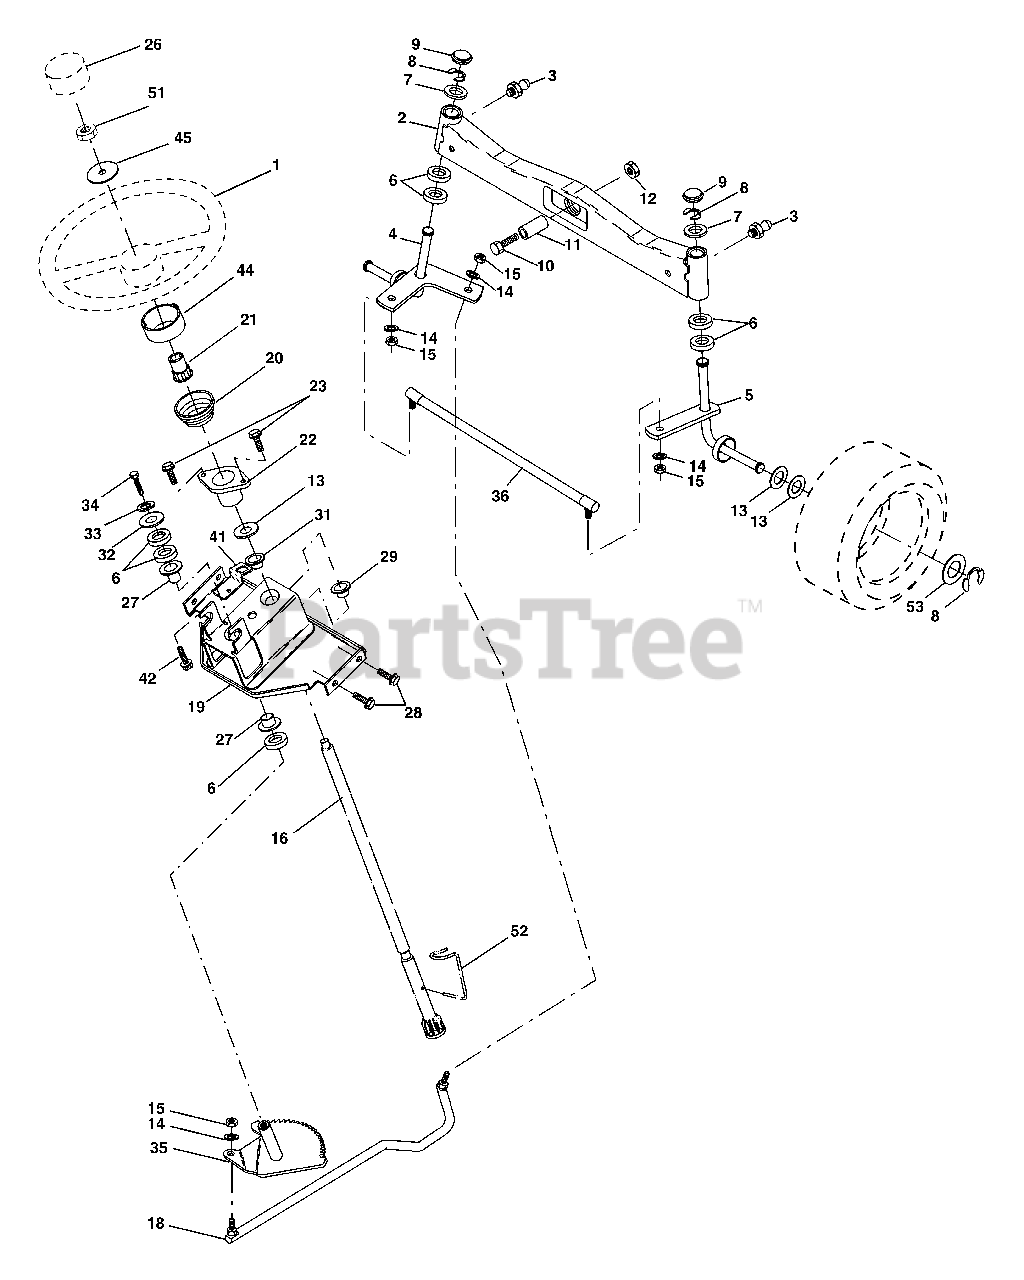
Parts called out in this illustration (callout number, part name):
1	Wheel, Steering
2	Axle Asm., Front
3	Fitting, Grease
4	Spindle Asm, LH
5	Spindle Asm., RH
6	Bearing, Race Thrust Harden
7	Washer 25/32 x 1-5/8 x 16 Ga.
8	Ring, Klip #T5304-75
9	Cap, Spindle
10	Bolt, Fin Hex 5/8-11 x 2-3/4
11	Spacer Brg Axle Front 1.570
12	Nut, Lock Flange 5/8-11 unc
13	Washer 25/32 x 1-1/4 x 16 Ga.
14	Washer, Lock Hvy Hlcl Spr 3/8
15	Nut Crownlock 3/8-24
16	Shaft Asm., Steering
19	Support Asm., Steering Vgt
20	Boot Steering
21	Adapter, Wheel Steering
22	Bushing, Strg.
26	Cap , Wheel Steering
27	Bearing, Col. Strg.
28	Screw 3/8-16 x 3/4
29	Bearing, Flange
31	Bushing, Nyliner Snap
32	Washer 11/32 x 1 x 10 Ga.
33	Washer, Lock Hvy Hlcl Spr 5/16
34	Bolt, Hex Hd 5/16-18 x 3/4
35	Gear, Sector Steering
41	Bracket Switch Inerlock VGT97
42	Screw 5/16-18 x 1/2
44	Extension Steering Premium
45	Washer 9/16 ID x 1-1/2 OD 11 Ga.
51	Nut Hex Jam Toplock 1/2-20 unf
52	Clip Steering
53	Washer Hardened
